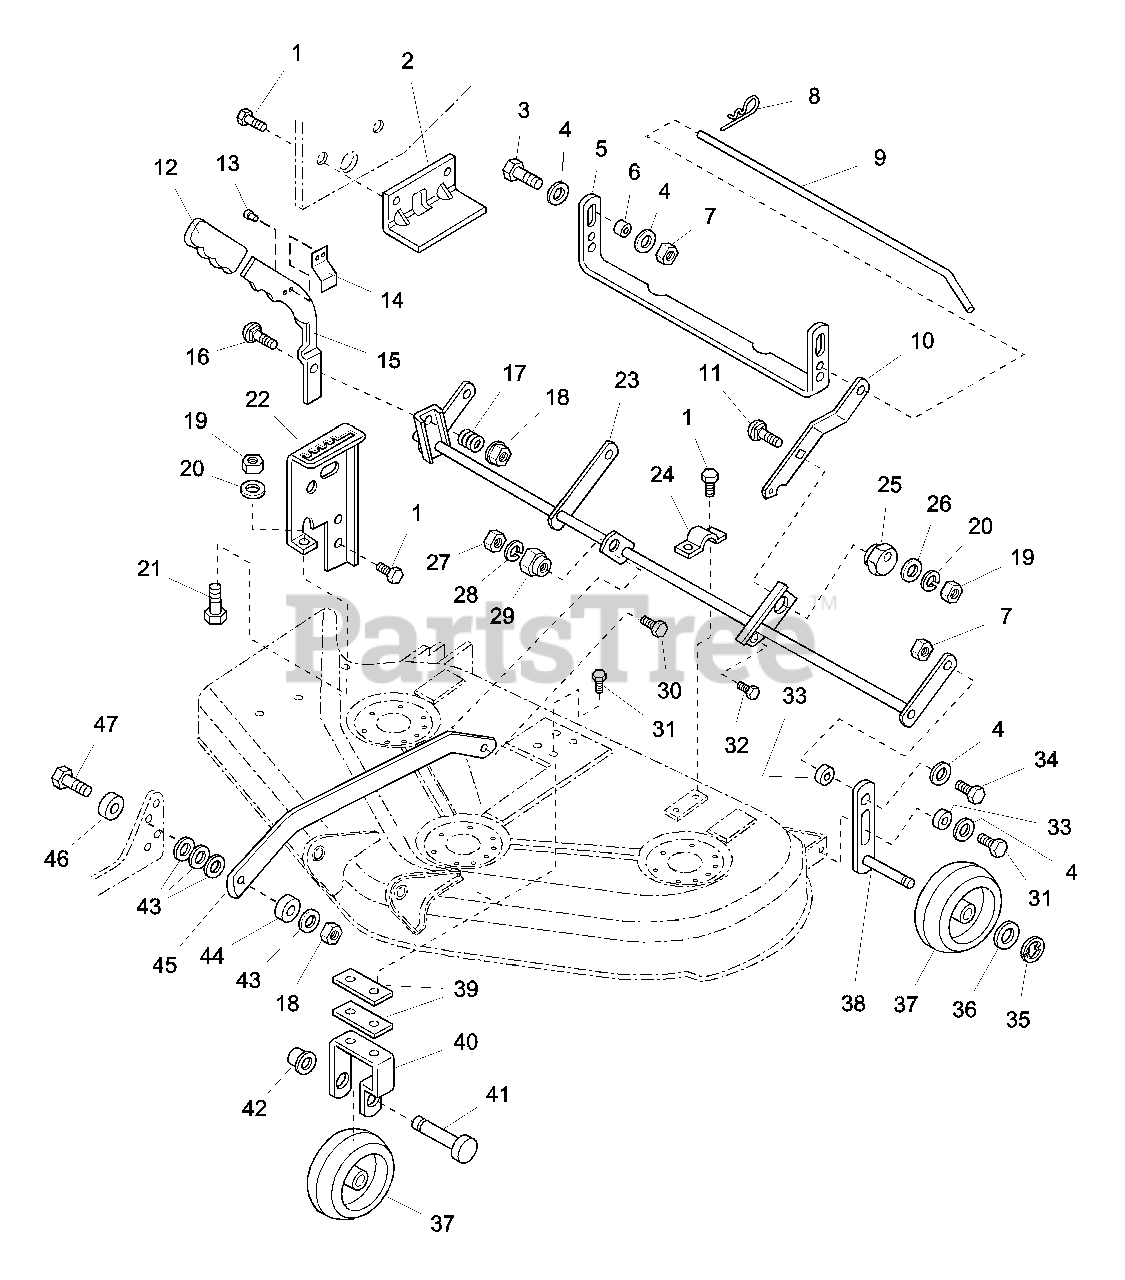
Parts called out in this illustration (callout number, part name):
1	CAPSCREW, Taptite Hex Washer Hd, 5/16-18 x 3/4
2	BRACKET, "L"
3	CAPSCREW, Hex Hd, 5/16-18 x 1-1/4
4	WASHER, 5/16
5	BRACKET, "U"
7	NUT, Hex Lock, 5/16-18
8	CLIP, Spring
9	ROD, Transport
11	CARRIAGE BOLT, 5/16-18 x 1-1/4
14	SPRING, Handle
15	ARM, Adjustment
16	CARRIAGE BOLT, 3/8-16 x 1-3/4
18	NUT, Hex Flange Whiz Lock Two Way, 3/8-16
19	NUT, Hex, Full, 5/16-18
20	LOCKWASHER, 5/16
21	CAPSCREW, Hex Hd, 5/16-18 x 3/4
23	ARM ASSEMBLY, Rocker
24	STRAP
26	WASHER, 5/16
27	NUT, Hex, 3/8
28	WASHER, Lock, 3/8
29	NUT, Hex Adjusting, .99 DIA .687
30	CARRIAGE BOLT, 3/8-16 x 1-1/2
31	CAPSCREW, Taptite Hex Washer Hd, 5/16-18 x 1
32	CAPSCREW, Taptite Hex Washer Hd, 5/16-18 x 7/8
34	CAPSCREW, Hex Hd, 5/16-18 x 1
35	E-RING, 1/2
36	WASHER, 1/2
37	WHEEL, Gauge
38	ARM ASSEMBLY
39	STRAP
40	BRACKET, Gauge Wheel
41	ROD, Mower Hitch
42	NUT, Push, 1/2
43	WASHER, 3/8
45	ARM, Pitch
47	CAPSCREW, Hex Hd, 3/8-16 x 2, Grade 5
